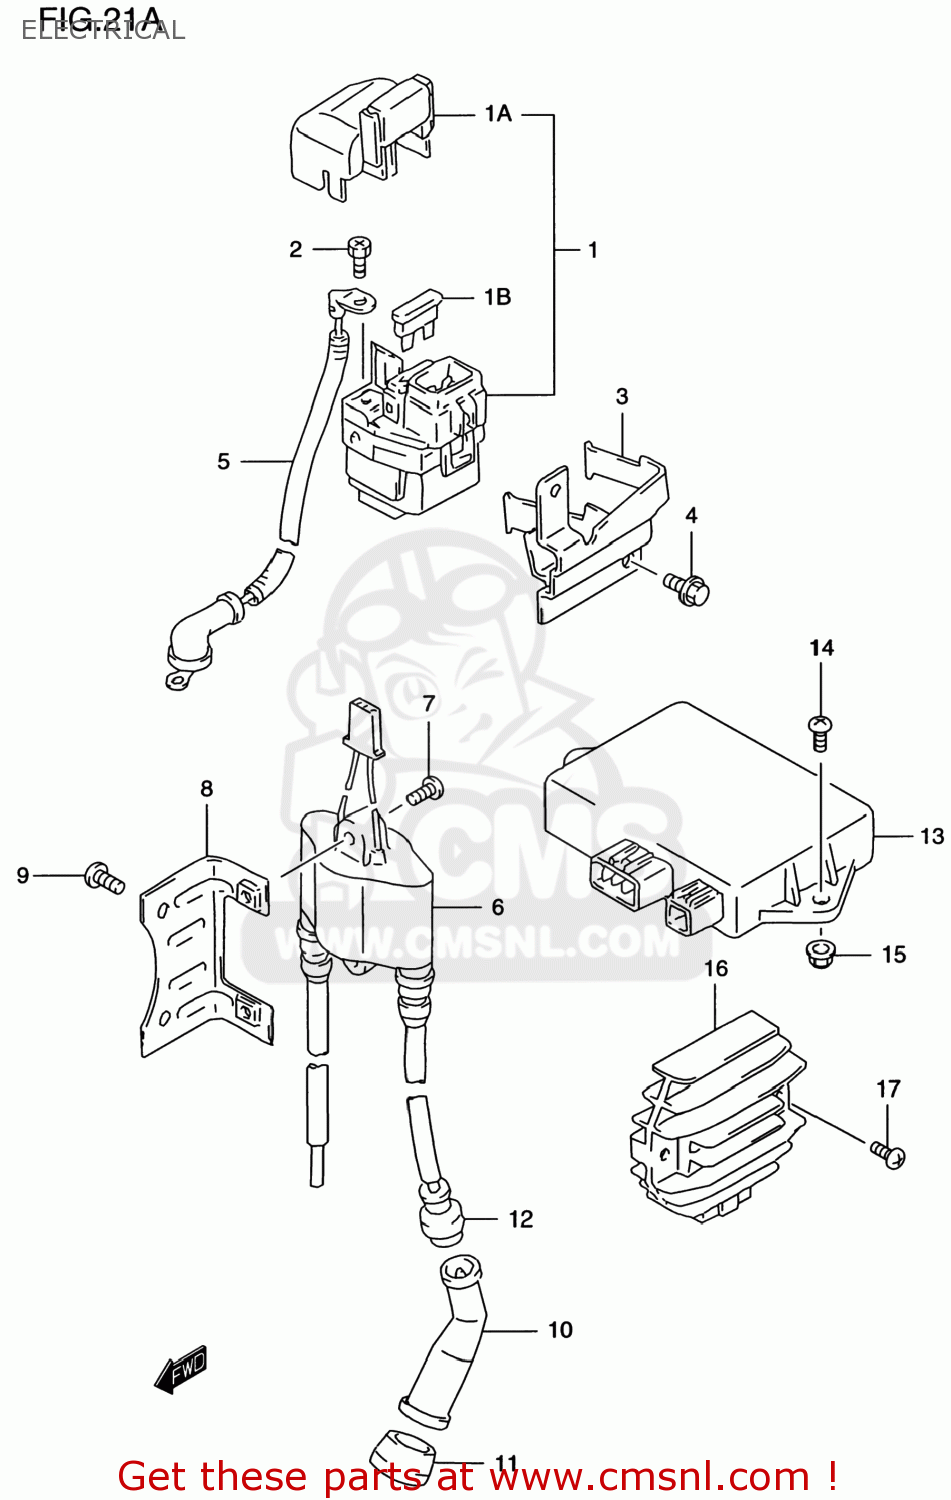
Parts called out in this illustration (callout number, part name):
1	RELAY ASSY,STARTING MOTOR
1A	COVER,STARTER RELAY
1B	FUSE(30A)
2	SCREW(6X8)
3	BRACKET,STARTING MOTOR RELAY
4	BOLT(6X8)
5	WIRE,STARTER MOTOR
6	COIL ASSY,IGNITION
7	SCREW
8	BRACKET,IGNITION COIL
9	SCREW 6X10
10	CAP,SPARK PLUG
11	SEAL,SPARK PLUG
12	SEAL,HIGH TENSION CORD
13	CDI UNIT
14	SCREW
15	NUT
16	RECTIFIER ASSY
17	SCREW
